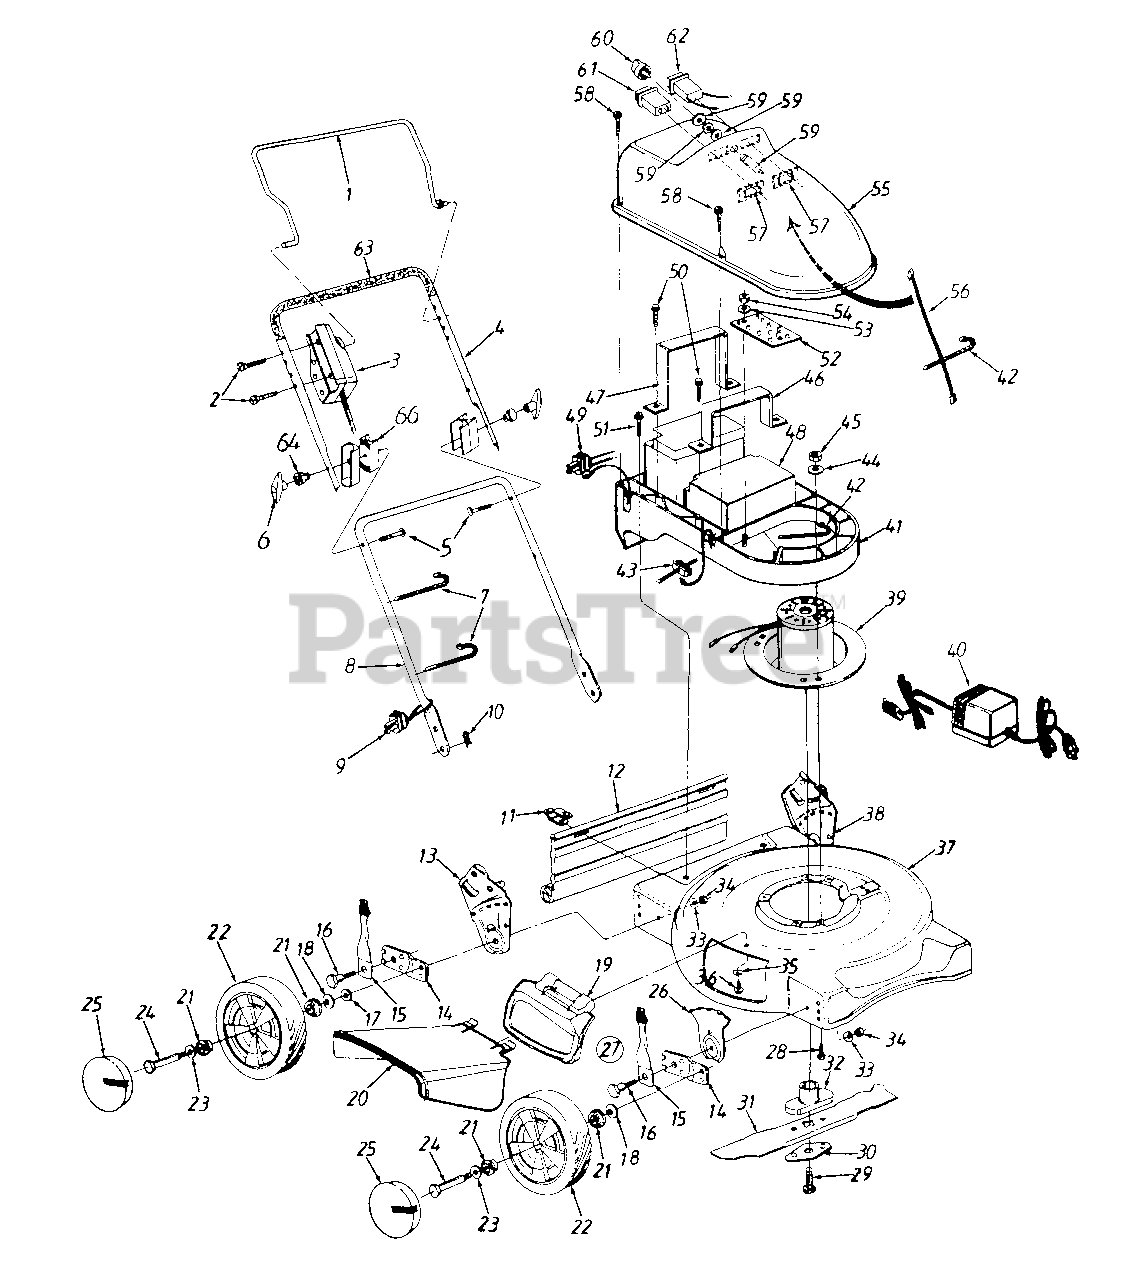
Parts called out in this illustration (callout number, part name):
3	Switch Ass'y.
6	Handle Knob
7	Cable Tie
9	Plug
10	Hairpin Clip
11	Hinge Clip
12	Rear Flap
13	Handle Brkt. Ass'y. - R.H.
15	Spring Lever Ass'y. w/Knob
16	Shld. Bolt .5" Dia. x .43" Lg.
17	Fl-Wash. .385" I.D. x 1" O.D.
18	Bell-Wash. .38" I.D. x .88" O.D.
19	Mulching Plug Ass'y.
20	Chute Deflector
21	Ball Bearing
22	Wheel Ass'y.
23	Wave Wash. .51" I.D. x .75" O.D.
24	Shld. Bolt .498" Dia. x 1.45
25	Hub Cap
26	Height Adj. Plate
27	Height Adj. Ass'y. Comp.- R.F.
28	Hex Wash. Self-Tap Scr. 3/8-16 x 1" Lg.
29	Hex Bolt 3/8-24 x 2.5" Lg.
30	Blade Bell Support
31	18" Blade
32	Blade Adapter
33	Bell-Wash. .39" I.D. x 1.38" O.D.
34	Hex Nut 3/8-16 Thd.
35	Bell-Wash. 1/4" I.D.
36	Hex Wash. Hd. TT-Tap Scr. 1/4 x .5" Lg.
39	Motor Ass'y.
40	Charger
41	Tray Ass'y.
42	Cable Tie
43	Harness Ass'y. Switch
44	Fl-Wash. .406" I.D.
45	Hex L-Nut 3/8-16 Thd.
46	Front Bracket Ass'y.
47	Rear Bracket Ass'y.
48	Battery Ass'y.
49	Charger Plug
50	Hex Hd. Hi-Lo Scr. 1/4 x .75" Lg.
51	Hex Wash. Hd. TT-Tap Scr. 1/4-20 x 1" Lg.
52	Circuit Board
53	Fl-Wash. .21" I.D. x .56" O.D.
54	Palnut Self-Threading
55	Motor Cover
56	Key Switch Harness Ass'y.
57	Mounting Clamp
58	Hex AB-Tap Scr. #10 x .75" Lg.
59	Key Switch
61	Meter
62	Meter
63	Foam Grip
64	Insulator Knob
66	Lower Handle Insulator
